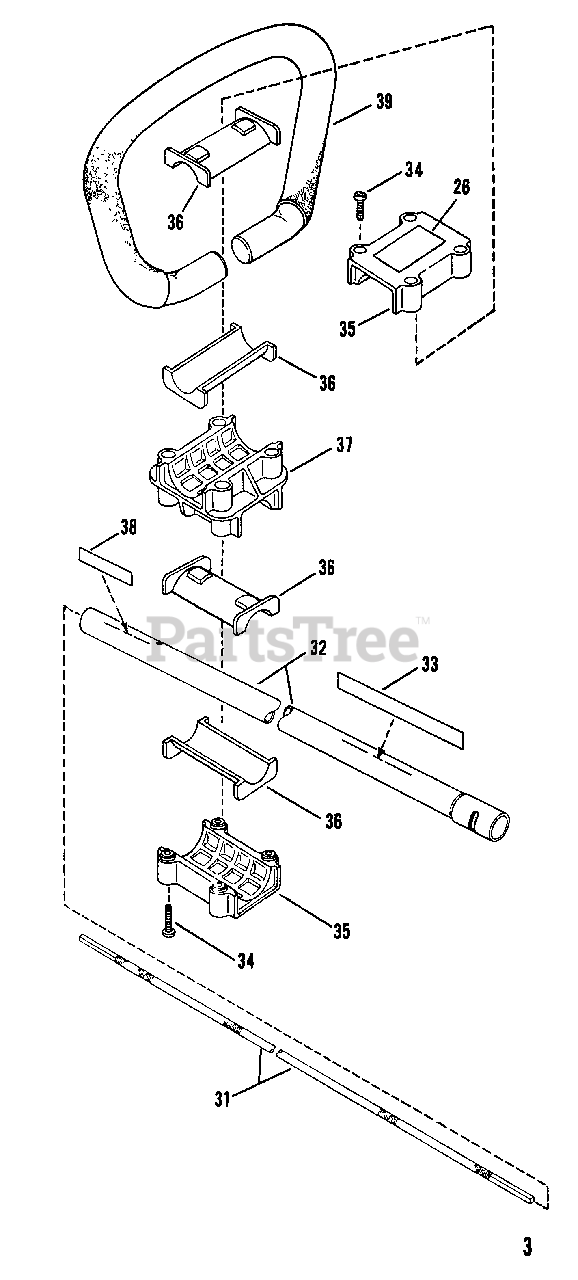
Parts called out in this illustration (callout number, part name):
26	Label, Replacement Part
31	SHAFT, Main, Flex (54.81" x .245:, .062 Square Ends x 1")
32	Assembly, Tubing
33	LABEL, Model 215SST
34	SCREW, #10-16 x 3/4"
35	HANDLE MOUNT, Cap
36	ISO-MOUNT,
37	HANDLE MOUNT, Center
38	LABEL-WARNING (Eye Protection)
39	HANDLE, ASSEMBLY, Loop
